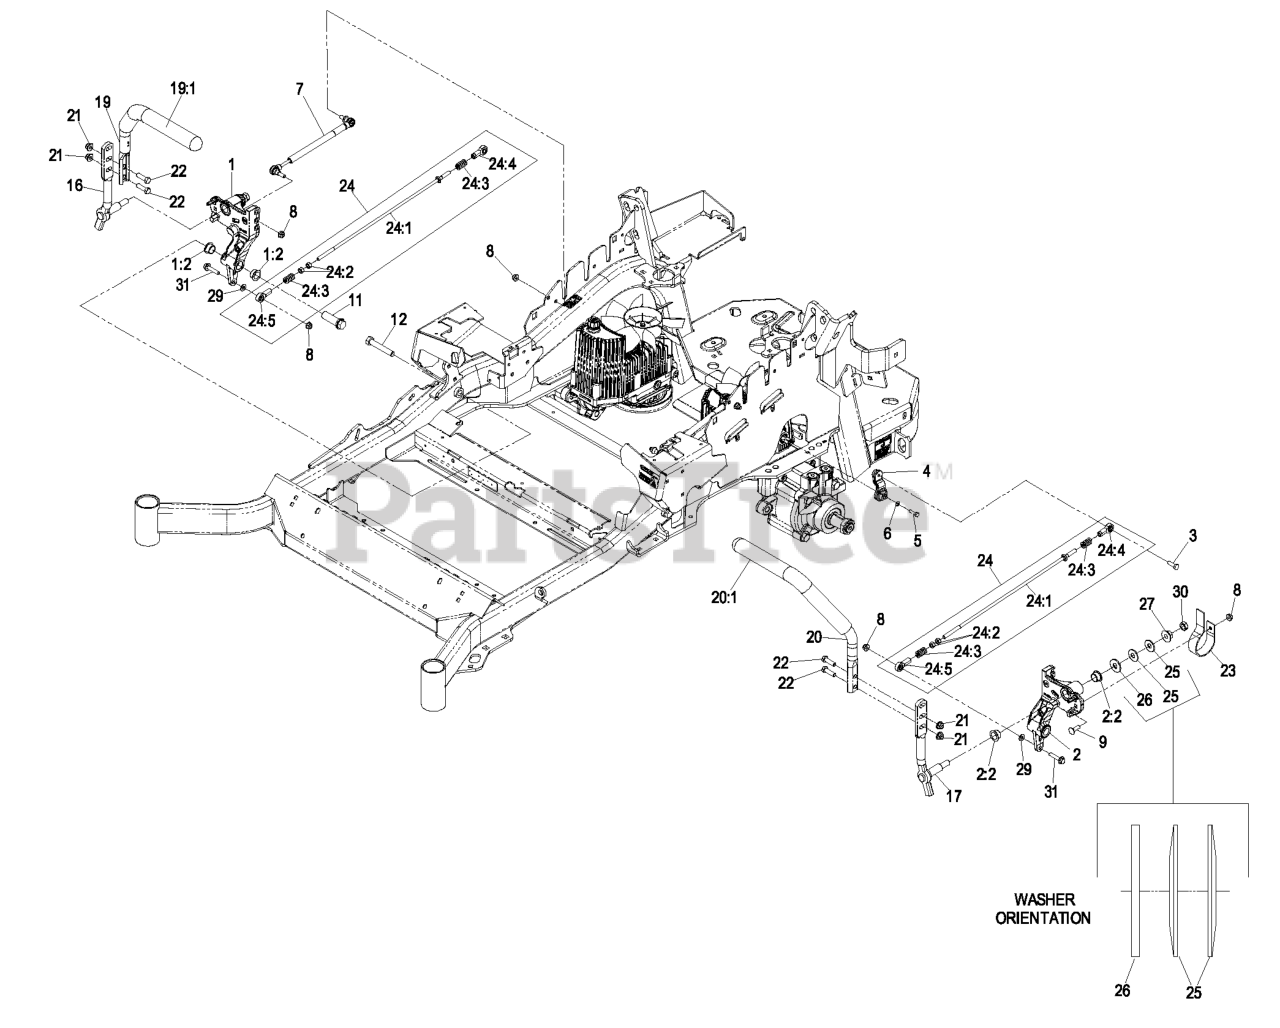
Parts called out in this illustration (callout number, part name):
1	RH MOTION CONTROL AND BUSHING ASM
1:2	BUSHING-FLANGE
2	LH MOTION CONTROL AND BUSHING ASM
2:2	BUSHING-FLANGE
3	SCREW-HH, THREAD LOCKING
4	ARM-CONTROL, PUMP
5	SCREW-HH
6	WASHER-SPRING
7	DAMPER-CONTROL, MOTION
8	NUT-HF, NI
9	BOLT-CARR
11	HUB-THREADED
12	SCREW-HH
16	LEVER-CONTROL MOTION, RH
17	LEVER-CONTROL MOTION, LH
19	RH STEERING HANDLE ASM
19:1	GRIP-LEVER, CONTROL
20	LH STEERING HANDLE ASM
20:1	GRIP-LEVER, CONTROL
21	NUT-HF, NI
22	SCREW-HH
23	SPRING-LEAF
24	FRONT PUMP LINKAGE ASM
24:2	NUT-HEX
24:3	SPRING-COMPRESSION
24:4	BALLJOINT-LH
24:5	BALLJOINT-RH
25	WASHER-SPRING
26	WASHER-FLAT
29	WASHER-PLAIN
30	NUT-JAM
31	SCREW-HHF
